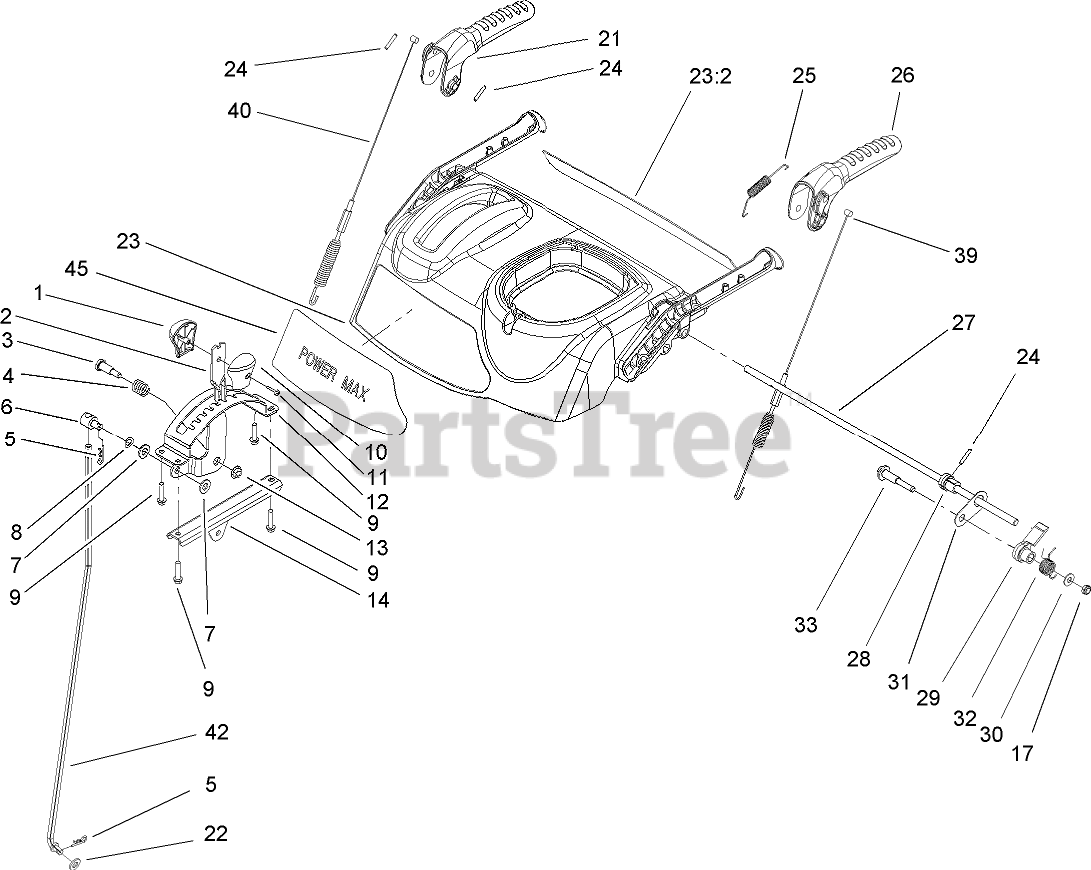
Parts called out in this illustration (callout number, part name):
1	KNOB-SHIFT, RH
2	SELECTOR-SPEED
3	SCREW-SHOULDER
4	SPRING-COMPRESSION
5	PIN-COTTER
6	TRUNNION
7	WASHER-FLAT
8	WASHER-SPRING
9	SCREW-PLASTITE
10	KNOB-SHIFT, LH
11	SCREW-PPH
12	GUIDE-SELECTOR, SPEED
13	NUT-HF
14	MOUNT-SELECTOR, SPEED
17	NUT-LOCK, NI
21	LEVER-AUGER
22	WASHER-FLAT
23	CONTROL PANEL ASM
23:2	DECAL-CONTROL PANEL
24	PIN-SPRING
25	SPRING-TENSION
26	LEVER-TRACTION
27	ROD-LOCKOUT
28	CAM-LOCKOUT
29	LATCH-LOCKOUT
30	WASHER-FLAT
31	LINK-LOCKOUT
32	SPRING-TORSION
33	SCREW-SHOULDER
39	CABLE-TRACTION
40	CABLE-AUGER
42	ROD-SHIFT
